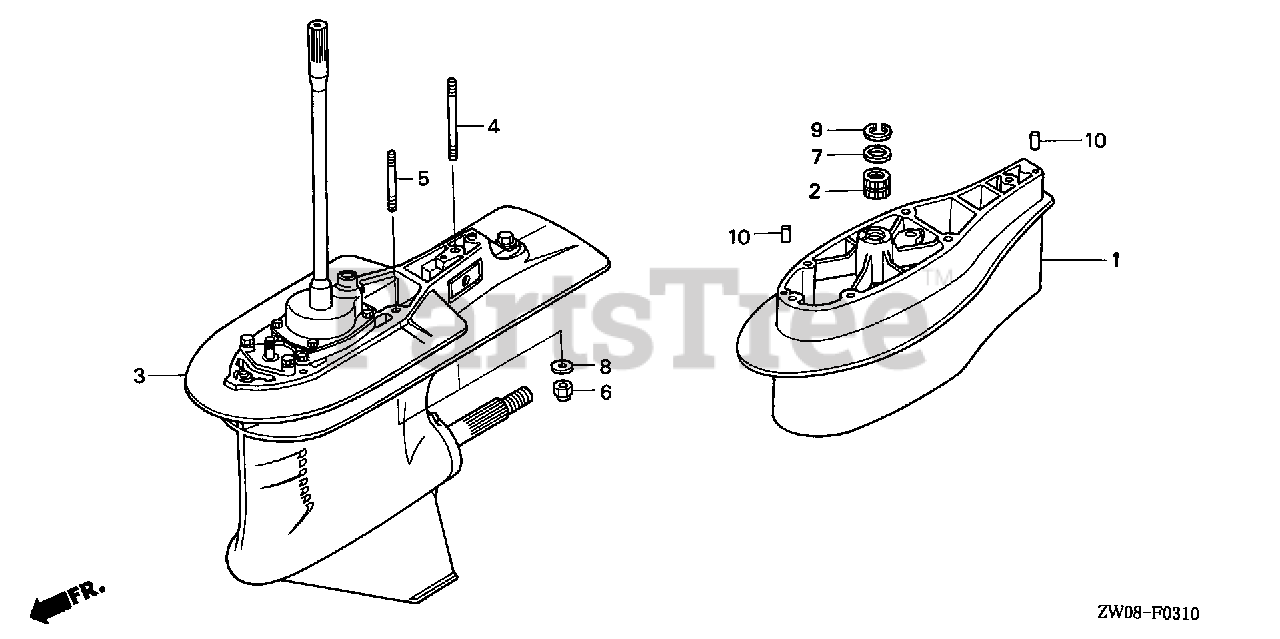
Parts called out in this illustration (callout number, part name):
1	SEPARATOR, EXTENSION *NH282MU* (UL) (OYSTER SILVER METALLIC-U)
2	BUSH, VERTICAL SHAFT
3	CASE ASSY., GEAR *NH282MU* (OYSTER SILVER METALLIC-U)
4	BOLT, STUD (10X202)
5	BOLT, STUD (10X164)
6	NUT, SELF-LOCK (10MM)
7	WASHER (26MM)
8	WASHER, PLAIN (10MM)
9	CIRCLIP (INNER) (40MM)
10	PIN, DOWEL (6X10)
